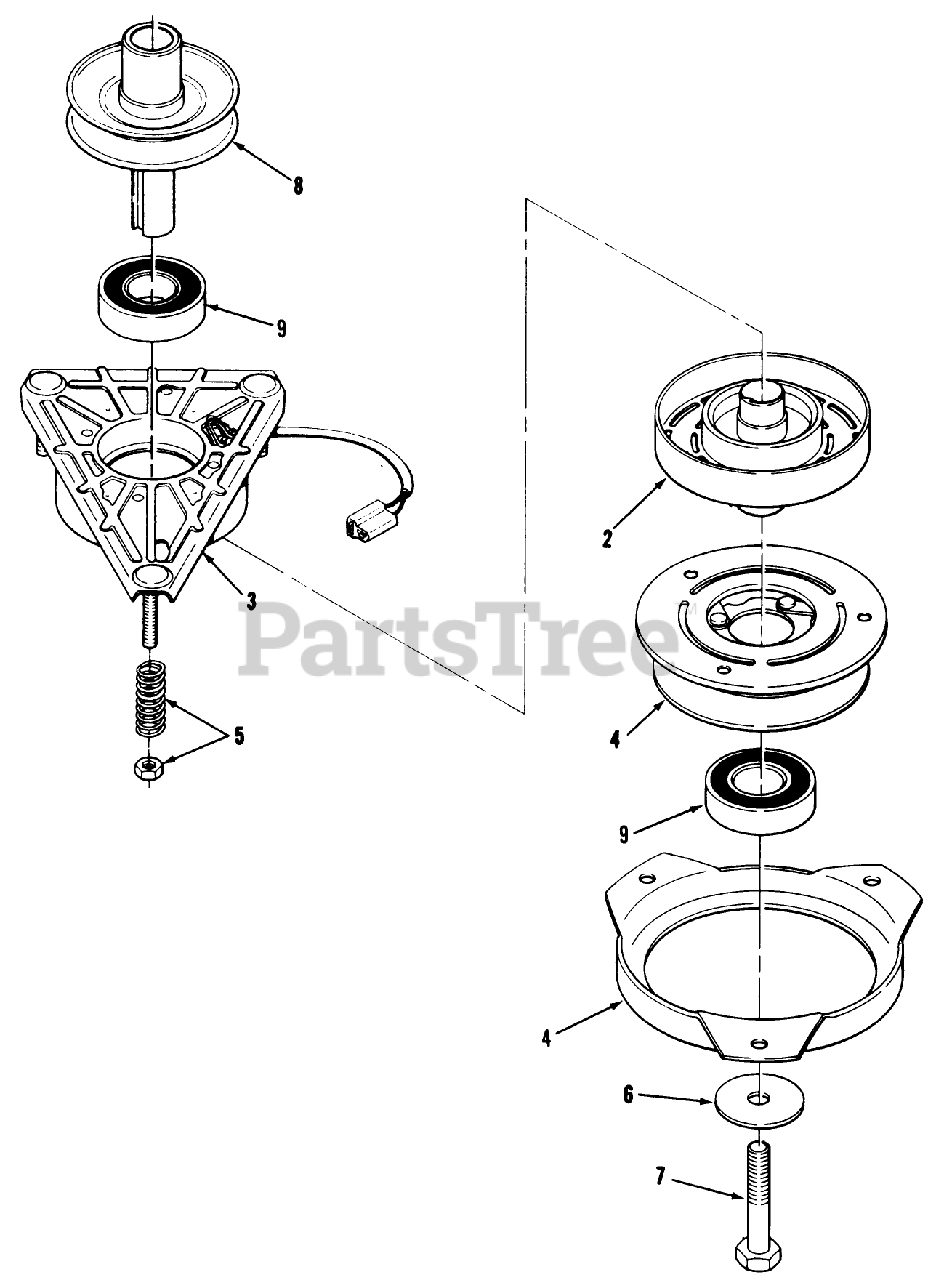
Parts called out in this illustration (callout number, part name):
1	Electric Clutch Assy (includes items 2, 3, 4 5)
2	Rotor Assy
4	ASS'Y-ARMATURE
5	ACCESS SPRING & NUT
6	WASHER
8	PULLEY-ENGINE
9	BEARING-ELEC CLUTCH
